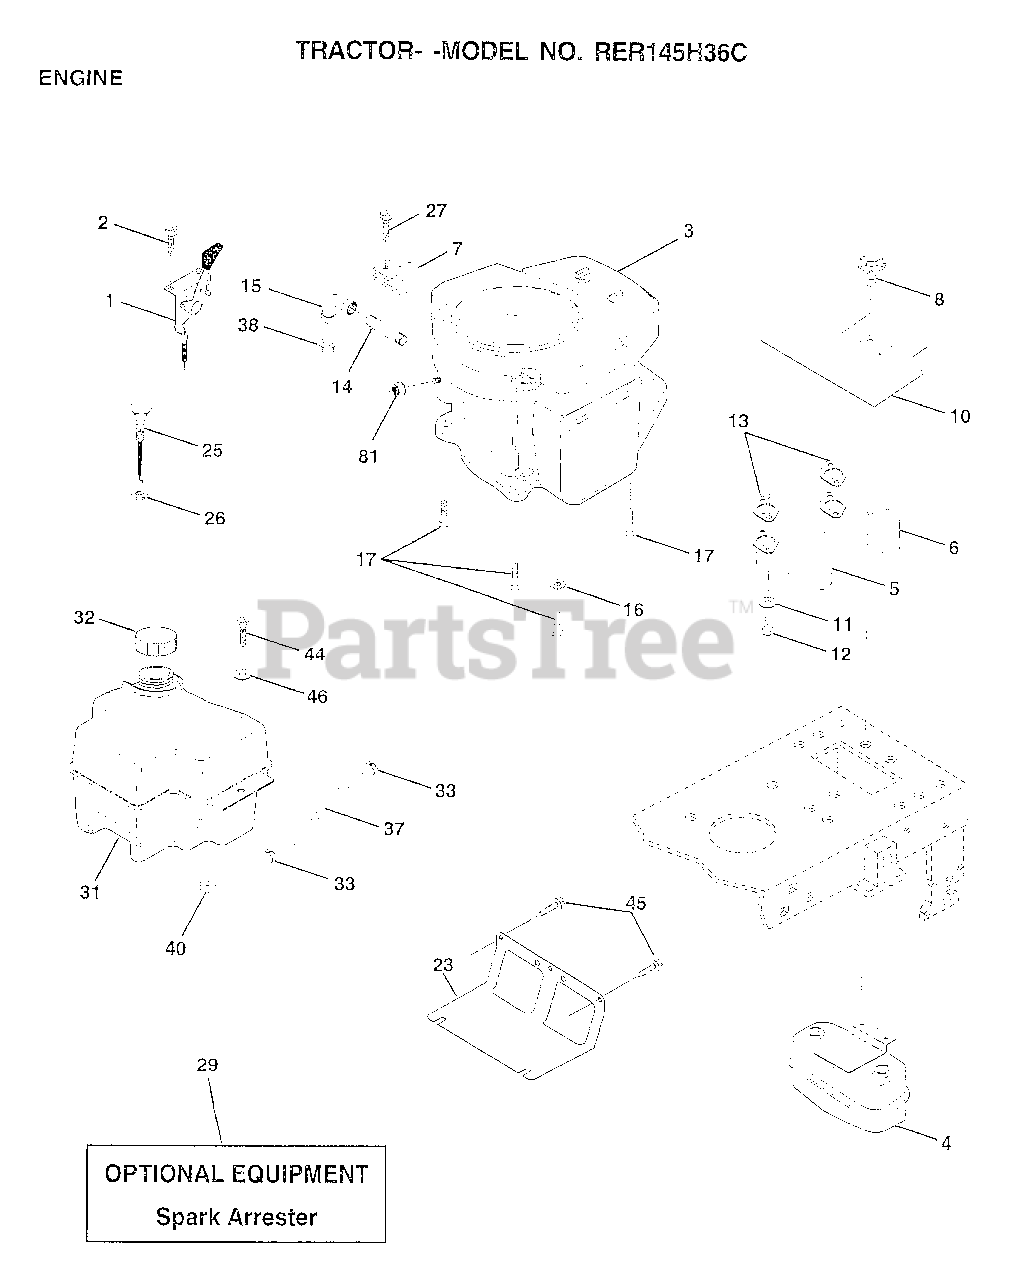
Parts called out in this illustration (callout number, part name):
1	CONTROL THRT 35.5
2	SCREW LT
4	MUFFLER.TW.LOTONE
5	EXHAUST.B&S.18.LH
6	EXHAUST.B&S.18.RH
7	CLAMP.TUBE.DBL.EN
8	BOLT.5/16-18.UNC
10	SHIELD.HEAT.
11	LOCKWASHER
13	GASKET MUFFLER
14	PIPE NIPPLE LT
15	ELBOW
16	LOCKWASHER
17	SCREW LT
23	SHIELD BROWNING
25	CONTROL.CHOKE.37
26	"NUT,KEPS 3/8-24IM"
27	"SCREW-TT,10-32 FL"
31	TANK.FUEL.FRONT.
32	CAP ASM FUEL
33	HOSE CLAMP
37	LINE FUEL
44	SCREW
45	SCREW
46	WASHER
81	NUT
